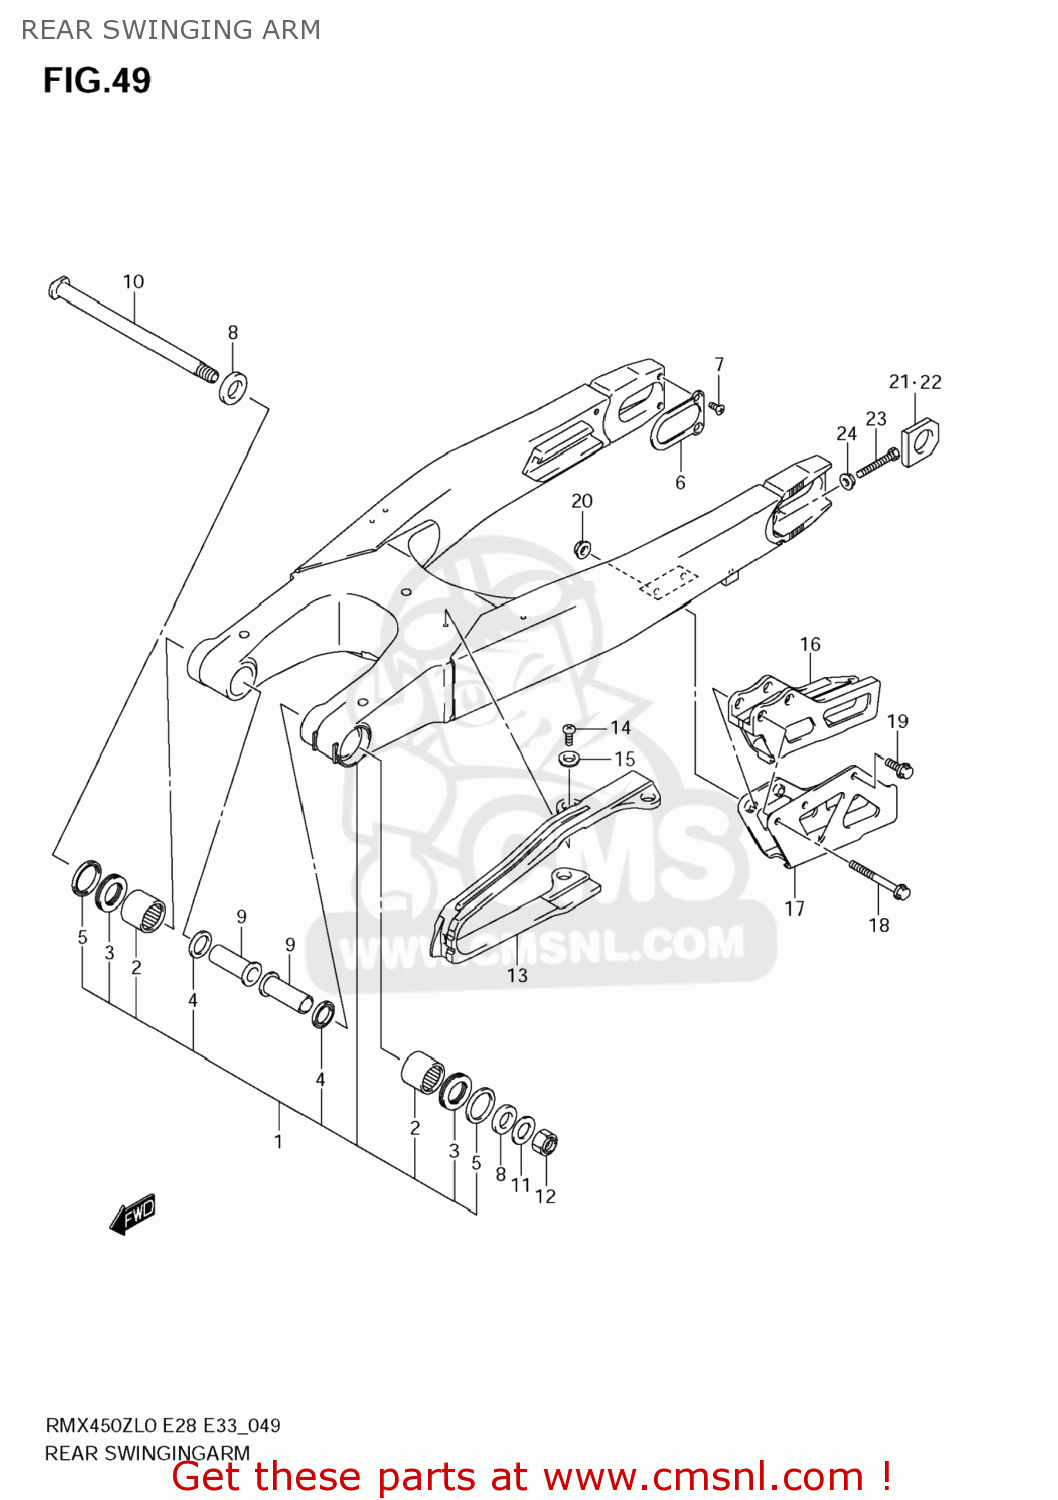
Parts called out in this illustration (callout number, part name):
1	SWINGINGARM ASSY,RR
2	BEARING(22X29X30)
3	BEARING(22X35X2)
4	SEAL,OIL(22X29X4)
5	SEAL,RR SWGARM PIVOT OUTER
6	PLATE,SWING ARM RR
7	SCREW
8	SPACER,RR SWGARM PIVOT OUTER
9	SPACER,SWGARM PIVOT INNER
10	SHAFT,RR SWINGINGARM PIVOT
11	WASHER
12	NUT
13	BUFFER,CHAIN TOUCH DEFENSE
14	SCREW
15	WASHER
16	GUIDE,CHAIN
17	PLATE,CHAIN GUIDE
18	BOLT(6X45)
19	BOLT(6X12)
20	NUT
21	WASHER,CHAIN A
22	WASHER,CHAIN A
23	BOLT(8X50)
24	NUT
